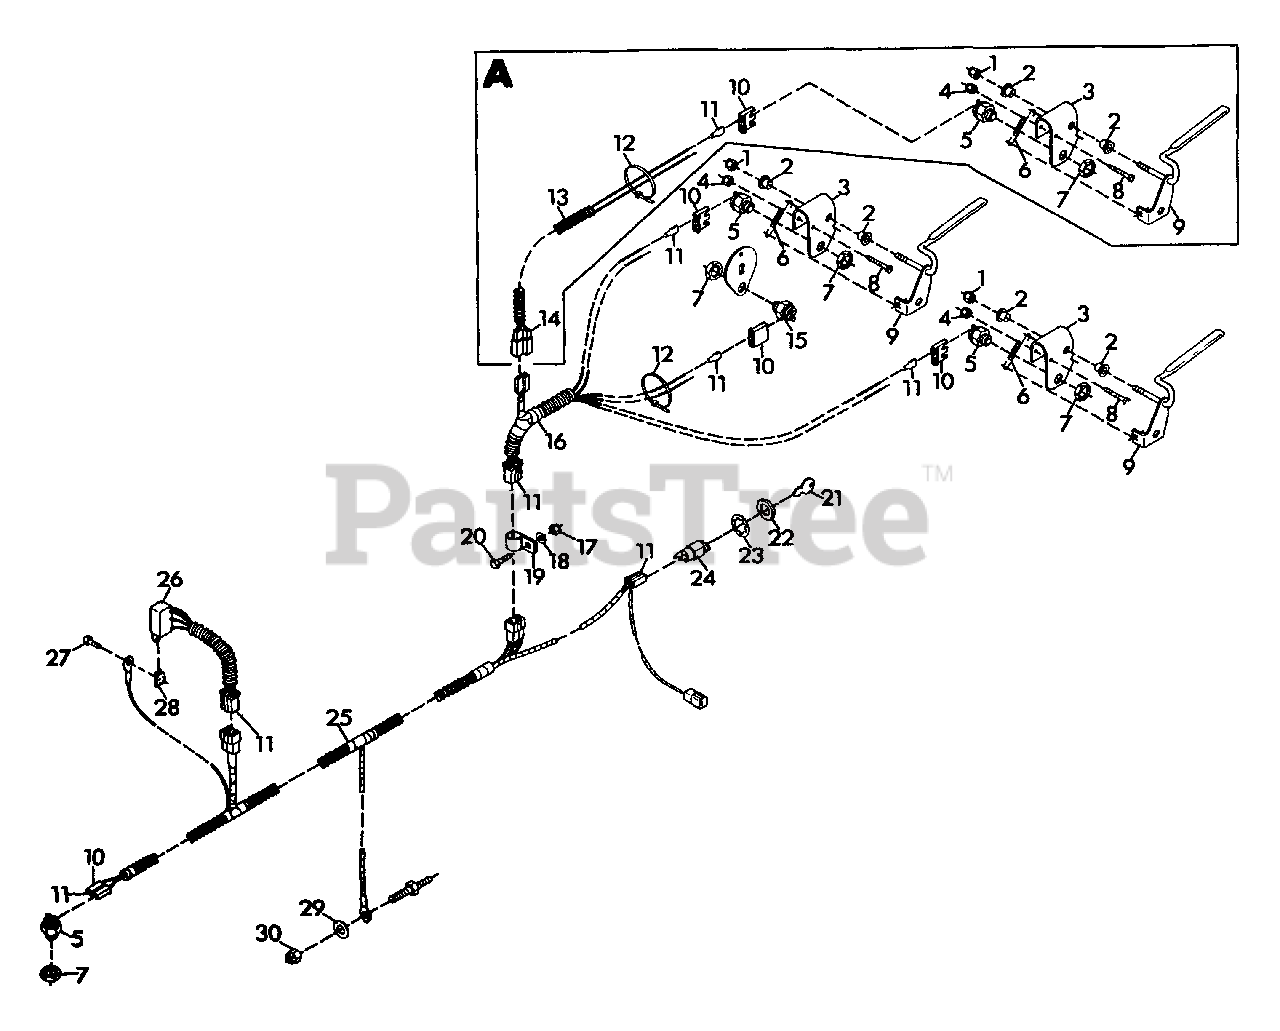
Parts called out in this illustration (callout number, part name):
1	Nut, Lock 5/16-18
2	Bushing, Interlock Lever
3	Bracket, Interlock Mounting
4	Nut, Lock 10-24
5	Switch, Interlock
6	Spring, Interlock Lever
7	Nut, Stamped 9/16-18
8	Screw, Machine 10-24 x 1.50
9	Weldment, Handle
10	Connector, 2-Wire Switch
11	Terminal
12	Tie Wrap, Black
13	Harness, Steering Brake
14	Connector
15	Switch, Neutral Start
16	Harness, Wiring Handlebar
17	Nut, Lock 1/4-20
18	Washer, Flat .281 x .625 x .065
19	Clamp, Nylon
20	Bolt, Hex 1/4-20 x .75
21	Key, Ignition Switch
22	Nut, Jam 5/8-32
23	Washer, Lock 5/8 Internal Tooth
24	Switch
25	Harness, Wiring
26	Module, Interlock Recoil
27	Bolt, Hex 1/4-20 x .625
28	Nut, Speed 1/4-20
29	Washer, Flat .469 x .938 x .065
30	Nut, Lock 3/8-16
